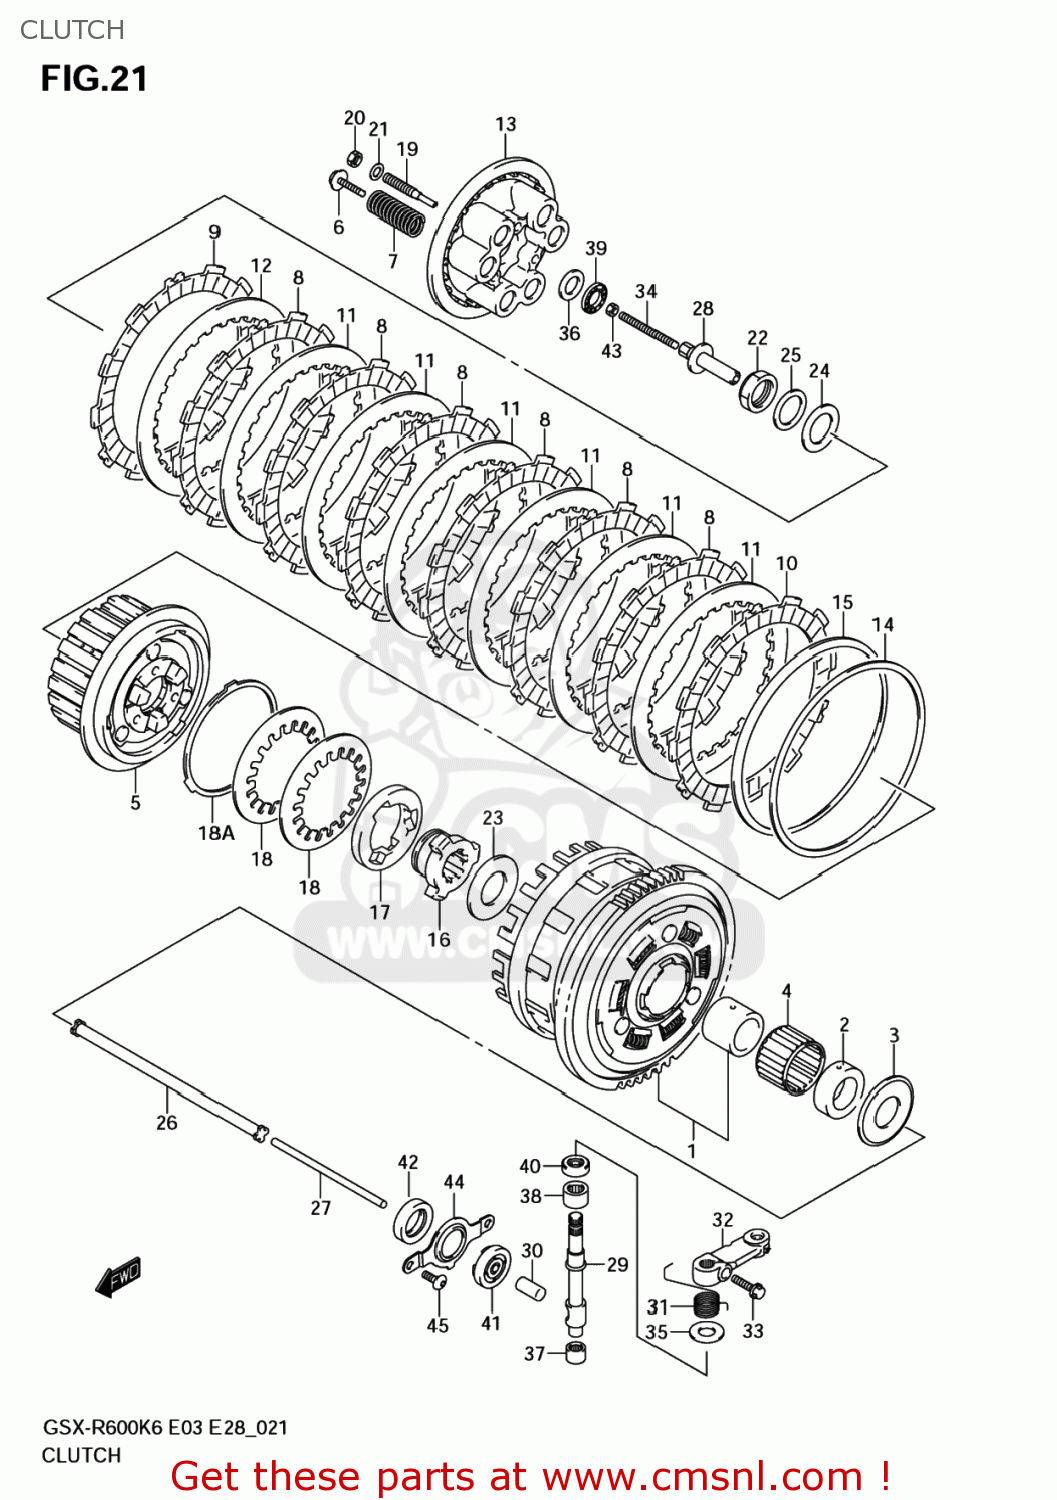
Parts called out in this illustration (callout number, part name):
1	GEAR ASSY,PRIM
2	SPACER,OIL PUMP DRIVE SPROCKET
3	WASHER(25X54X2.4)
4	BEARING(35X40X26.8)
5	HUB,CLUTCH SLEEVE
6	BOLT,CLUTCH SPRING
7	SPRING,CLUTCH
8	PLATE,CLUTCH DRIVE NO.1 (NAS)
9	PLATE,CLUTCH DRIVE NO.2 (NAS)
10	PLATE,CLUTCH DRIVE NO.3 (NAS)
11	PLATE,CLUTCH DRIVEN (NAS)
12	PLATE,CLUTCH DRIVEN(T:2.3) (NAS)
13	DISC,CLUTCH PRESSURE
14	SEAT,WAVE WASHER
15	WASHER,CLUTCH PLATE WAVE
16	CAM,CLUTCH DRIVE
17	CAM,CLUTCH DRIVEN
18	WASHER,CAM REACTION WAVE
18A	WASHER,CAM REACTION SEAT
19	LIFTER,CLUTCH PRESSURE DISC
20	NUT,CL PRESS DISC LIFTER LOCK
21	SHIM(8.8X14X1)
22	NUT
23	WASHER(25X50X2.5)
24	WASHER
25	WASHER(25X41X2.5)
26	ROD,CLUTCH PUSH,R
27	ROD,CLUTCH PUSH,L
28	PIECE,CLUTCH PUSH
29	CAMSHAFT,CLUTCH RELEASE
30	CAP,CLUTCH PUSH ROD
31	SPRING,CLUTCH RELEASE RETURN
32	ARM,CLUTCH REL
33	BOLT(6X20)
34	SCREW. CLUTCH P
35	WASHER. CLUTCH
36	WASHER(15.5X28X1)
37	BEARING(10X14X10)
38	BEARING(12X18X12)
39	BEARING(15X28X2)
40	SEAL,OIL(10X20X6)
41	SEAL,OIL(6X34X10)
42	SEAL,OIL(10X17X5)
43	NUT
44	RETAINER,CL PUSH ROD OIL SEAL
45	SCREW(6X13)
